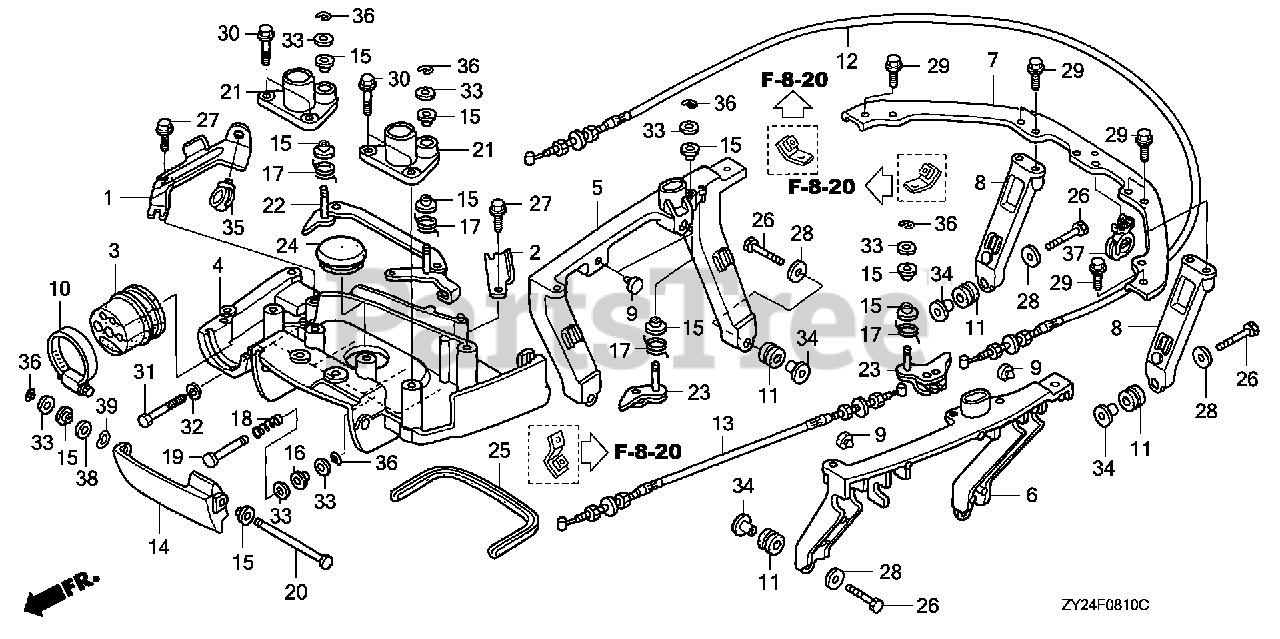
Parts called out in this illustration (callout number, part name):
1	BRACKET, CABLE
2	PLATE, STARTER CABLE
3	GROMMET A, CASE (LOWER)
4	BRACKET, FR. COVER *NH8* (DARK GRAY)
5	BRACKET, R. SIDE COVER
6	BRACKET, L. SIDE COVER
7	BRACKET A, RR. COVER
8	BRACKET B, RR. COVER
9	RUBBER, STOPPER
10	BAND, CASE GROMMET (LOWER)
11	RUBBER, FR. CARRIER CUSHION
12	CABLE A, COVER LOCK
13	CABLE B, COVER LOCK
14	LEVER, COVER LOCK *NH282MU* (OYSTER SILVER METALLIC-U)
15	BUSH A, COVER LOCK
16	BUSH B, COVER LOCK
17	SPRING, COVER LOCK HOOK
18	SPRING, LOCK LEVER RETURN
19	SHAFT, COVER OPEN
20	SHAFT, FR. LOCK
21	HOLDER, STRIKER
22	LOCK ASSY., FR.
23	LOCK, SIDE
24	CAP, L. SIDE COVER
25	SEAL D, COVER (LOWER)
26	BOLT, HEX. (8X35)
27	BOLT, FLANGE (6X14)
28	WASHER, PLAIN (8MM)
29	BOLT, FLANGE (6X12)
30	BOLT, FLANGE (6X20)
31	BOLT, HEX. (8X25)
32	WASHER, PLAIN (8MM)
33	WASHER, PLAIN (8MM)
34	COLLAR (8.5X14.5)
35	CLIP, WIRE HARNESS (BLACK)
36	E-RING (6MM)
37	CLIP, HARNESS
38	WASHER, PLAIN (10MM)
39	WASHER, WAVE (10MM)
